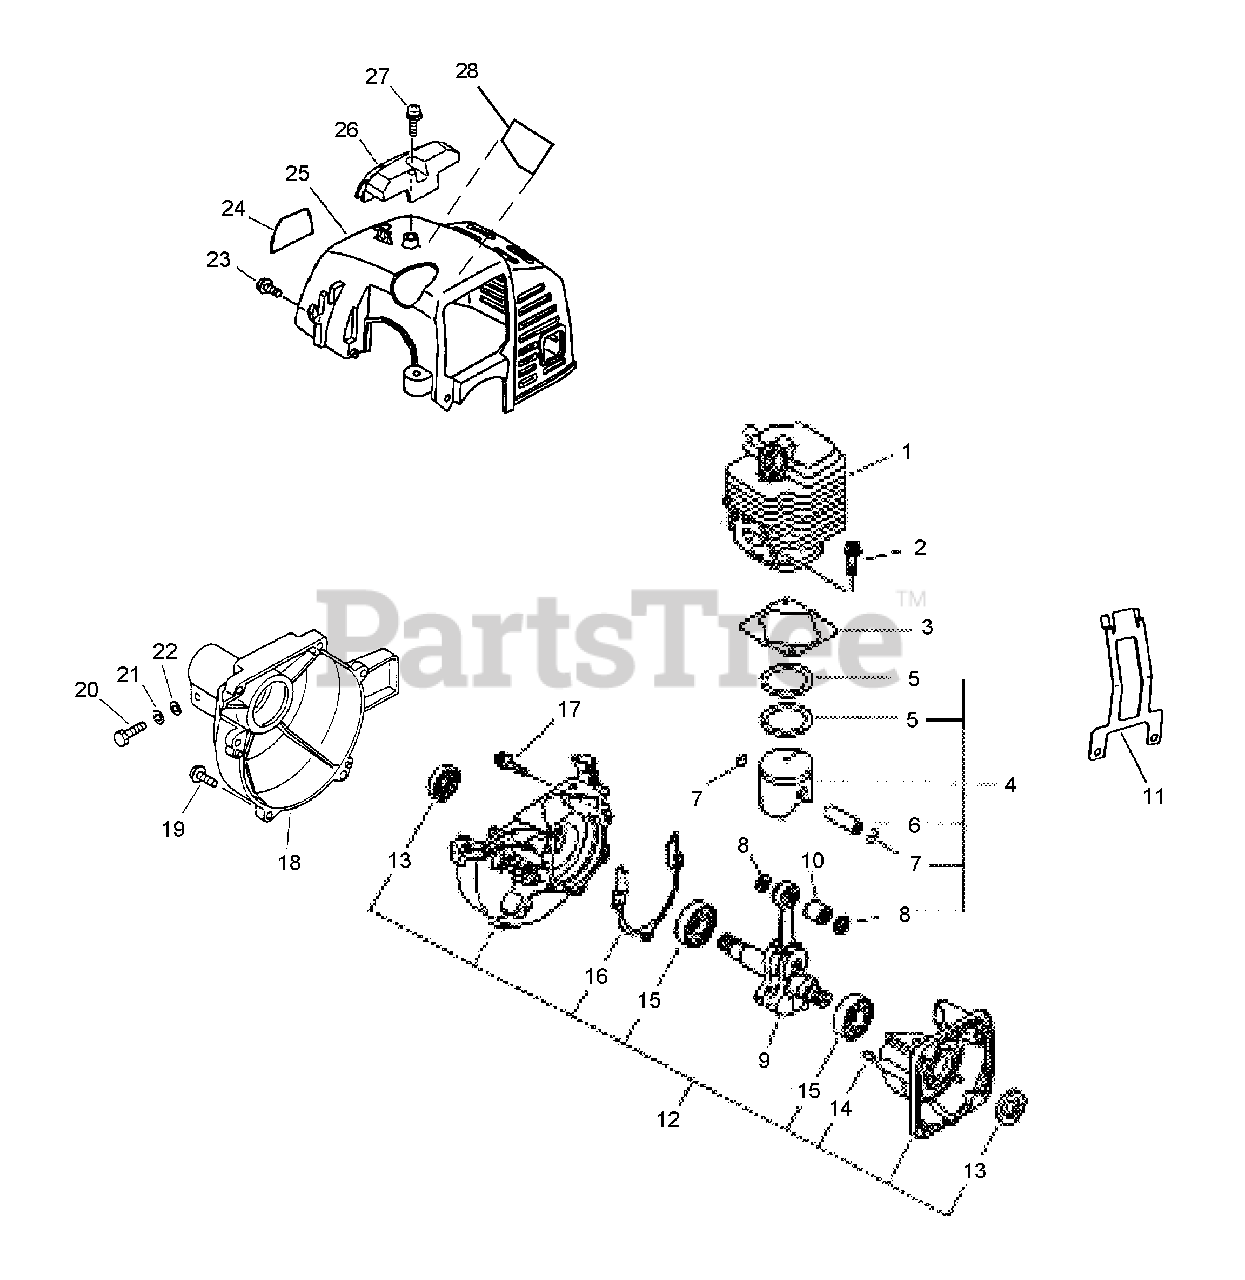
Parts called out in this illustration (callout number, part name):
1	CYLINDER
2	BOLT 5×22
3	GASKET, CYLINDER
4	PISTON KIT
5	RING, PISTON
6	PIN, PISTON 8
7	RING, SNAP
8	WASHER, THRUST
9	CRANKSHAFT ASSY
10	BEARING, NEEDLE
11	GUARD, ENGINE
12	CRANKCASE ASSY
13	SEAL, OIL 12
14	PIN, LOCATING 4
15	BEARING, BALL - 6201 C3
16	GASKET, CRANKCASE
17	BOLT 5×28
18	CASE, FAN
19	BOLT 4×16
20	BOLT 5×25
21	WASHER, SPRING 5
22	WASHER, FLAT 5.5×10×0.8
23	SCREW 4×12
24	LABEL - MODEL
25	COVER, ENGINE - ORANGE
26	GUARD, TOP - BLACK
27	SCREW 5×16
28	LABEL, CAUTION
